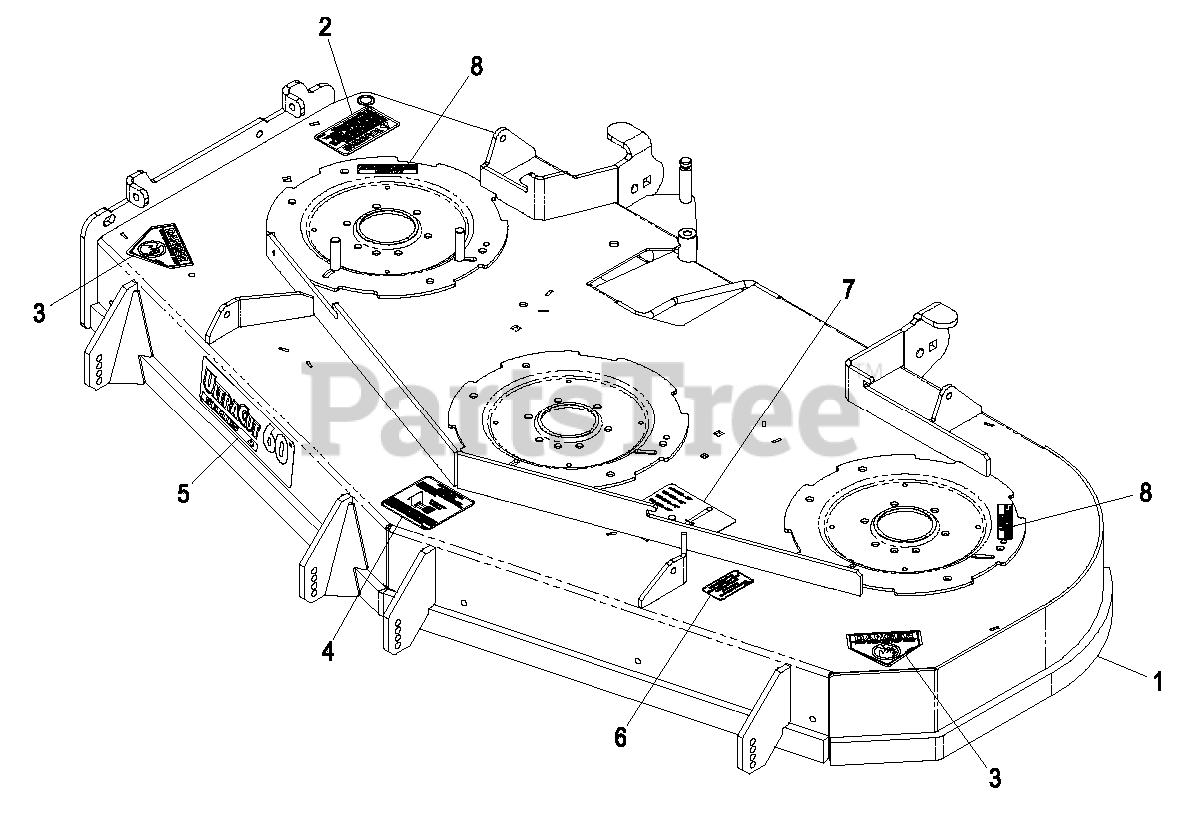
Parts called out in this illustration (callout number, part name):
2	DECAL-WARNING, DISCHARGE
3	DECAL-DANGER
4	DECAL,ANTISCALP
5	DECAL,ULTRACUT 60 SERIES
6	DECAL,BOLT TORQUE
7	DECAL,BELT ROUTING
8	DECAL-COVER, MISSING
